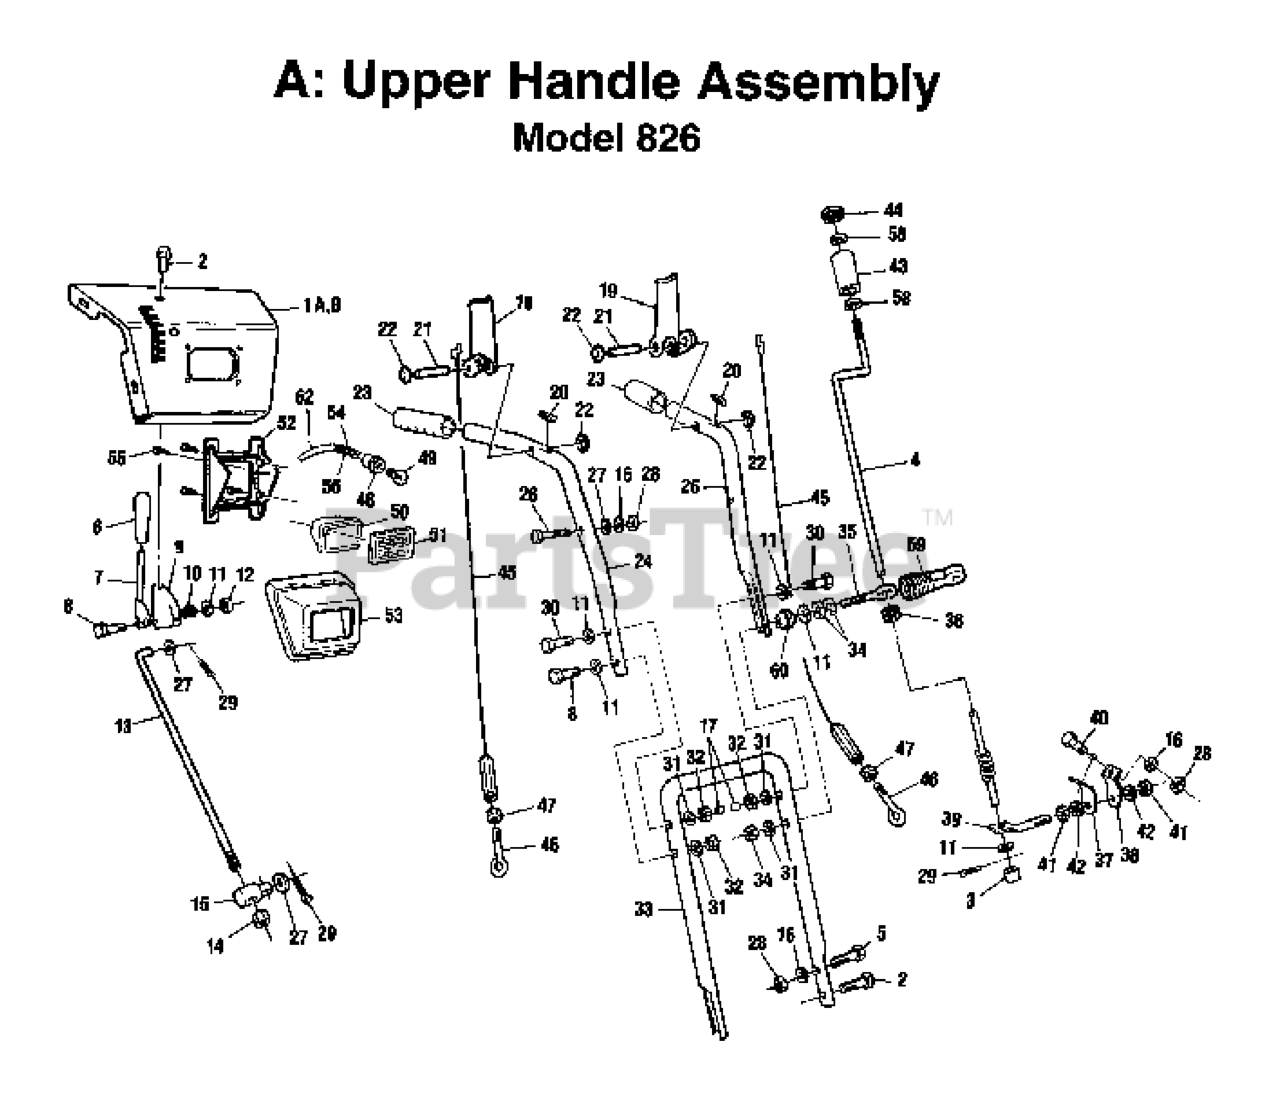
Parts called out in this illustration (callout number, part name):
5	BOLT.FIN.HEX.5/16-18X3/4
8	BOLT
16	WASHER.LOCK.HVY.HLCL.SPR.5/16
28	LOCKNUT
29	COTTER PIN
30	BOLT.HEX.FIN.3/8-16 X 3.GR5
31	WASHER, LOCK 3/8
32	NUT.HEX.3/8-16UNC
40	Bolt - Rd. Hd. Sq. Neckiage 3/8 16 x 3/4
42	LOCKWASHER
